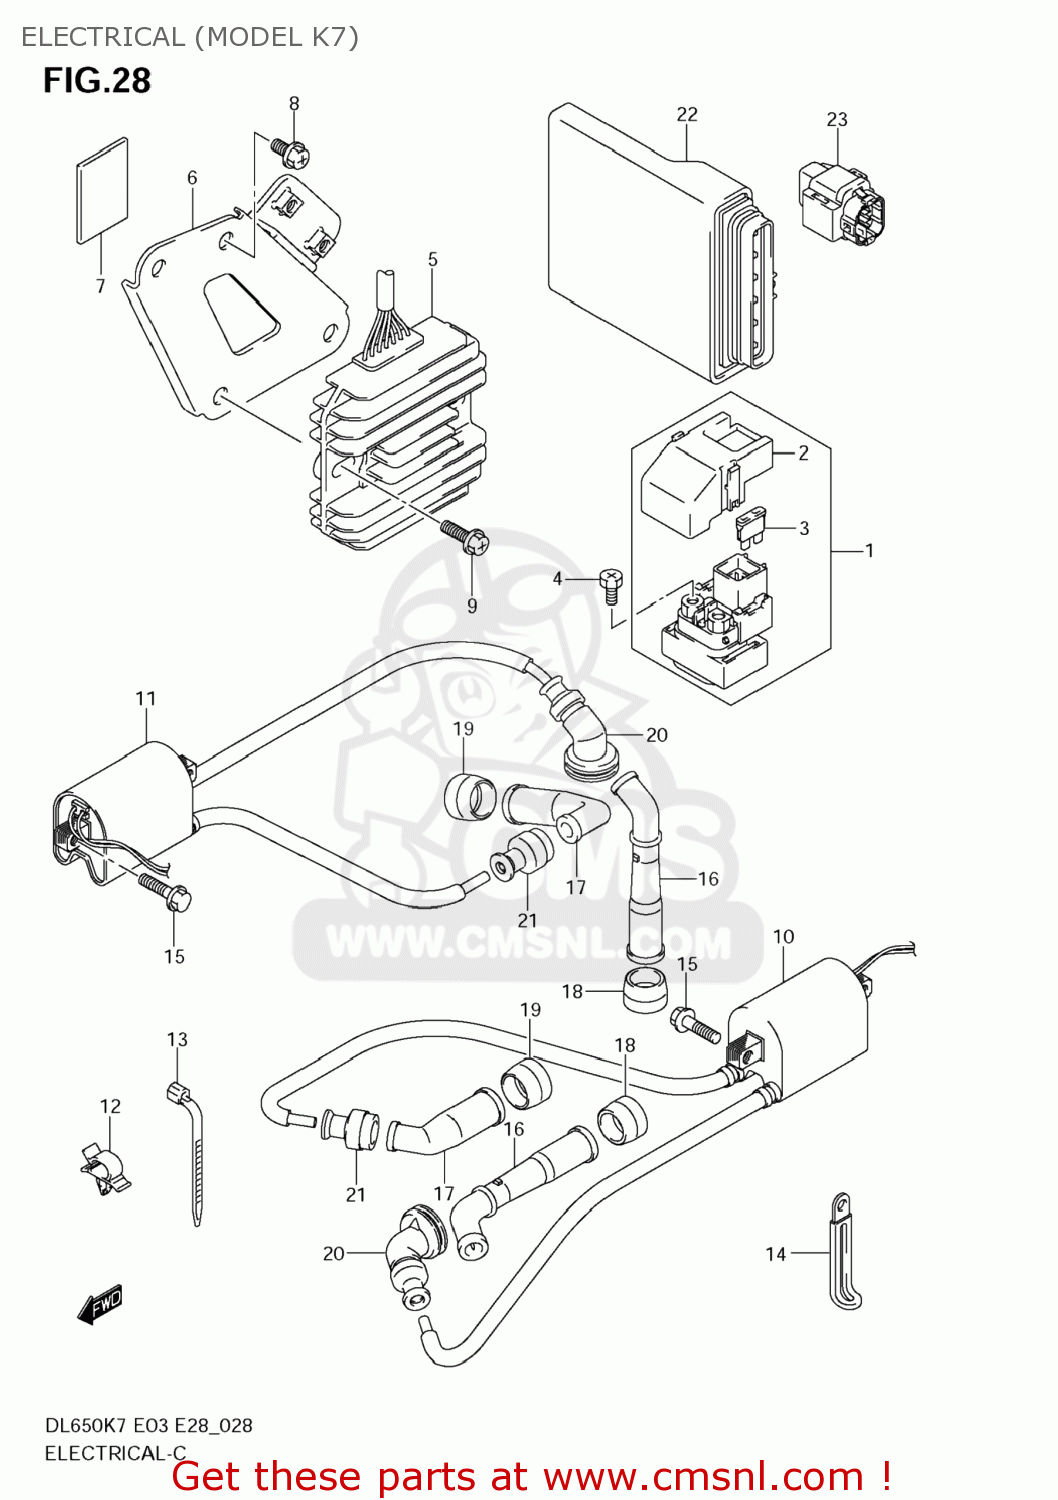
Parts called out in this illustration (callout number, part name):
1	RELAY ASSY,STARTING MOTOR
2	COVER
3	FUSE(30A)
4	SCREW(6X8)
5	RECTIFIER ASSY
6	BRACKET,RECT FTG
7	PROTECTOR(170X95X3.0)
8	BOLT
9	SCREW
10	COIL ASSY,IGNITION FR
11	COIL ASSY,IGNITION RR
12	CLAMP
13	CLAMP(L:165)
14	CLAMP(L:45)
15	BOLT
16	CAP ASSY,SPARK PLUG
17	CAP ASSY,SPARK PLUG
18	SEAL,SPARK PLUG CAP
19	SEAL,SPARK PLUG
20	SEAL,HIGH TENS
21	SEAL,HIGH TENSION CORD
22	CONTROL UNIT, FI
23	SENSOR ASSY,FUEL CUT
